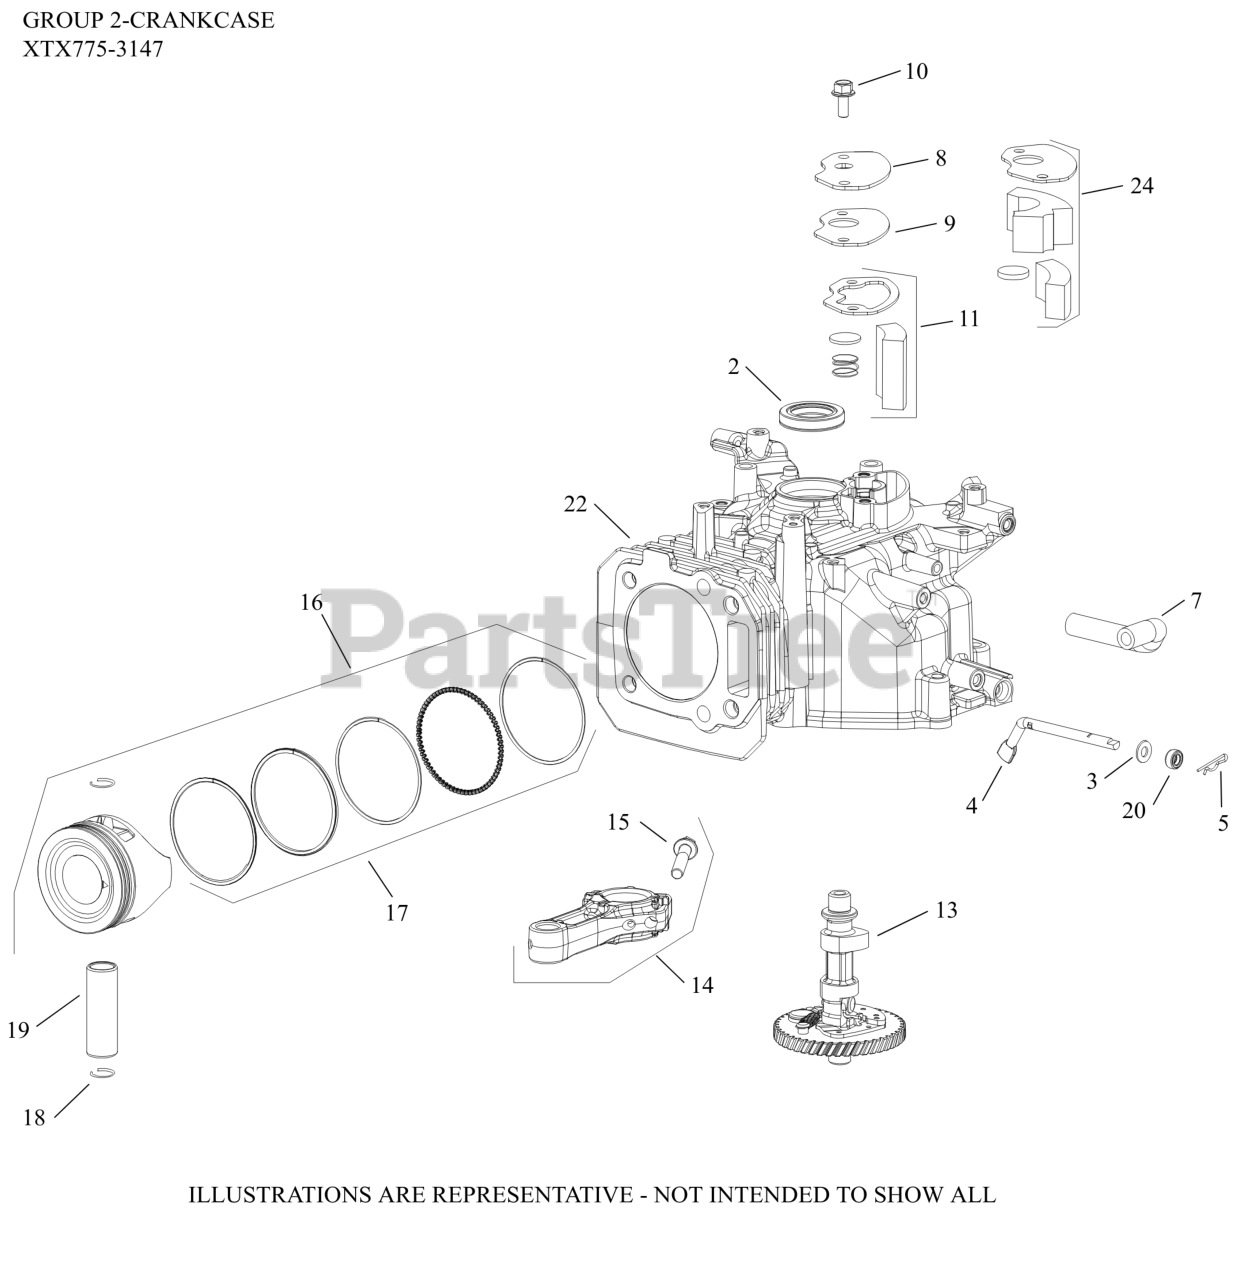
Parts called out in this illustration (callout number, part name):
2	SEAL, CCASE/FLYWHEEL
3	WASHER, FLAT (DIA 13mm O.D.)
4	SHAFT, GOVERNOR CROSS
5	CLIP, GOVERNOR SHAFT
7	HOSE, BREATHER
8	COVER, BREATHER
9	GASKET, BREATHER COVER
10	SCREW, HEX FLANGE (M6)-USE 25 086 433-S
11	KIT, BREATHER FILTER
13	CAMSHAFT ASSEMBLY
14	CONNECTING ROD
15	SCREW, HEX FLANGE (M7)
16	KIT, PISTON
18	RETAINER, PISTON PIN
19	PIN, PISTON
20	SEAL, OIL
22	CRANKCASE
24	KIT, BREATHER FILTER
